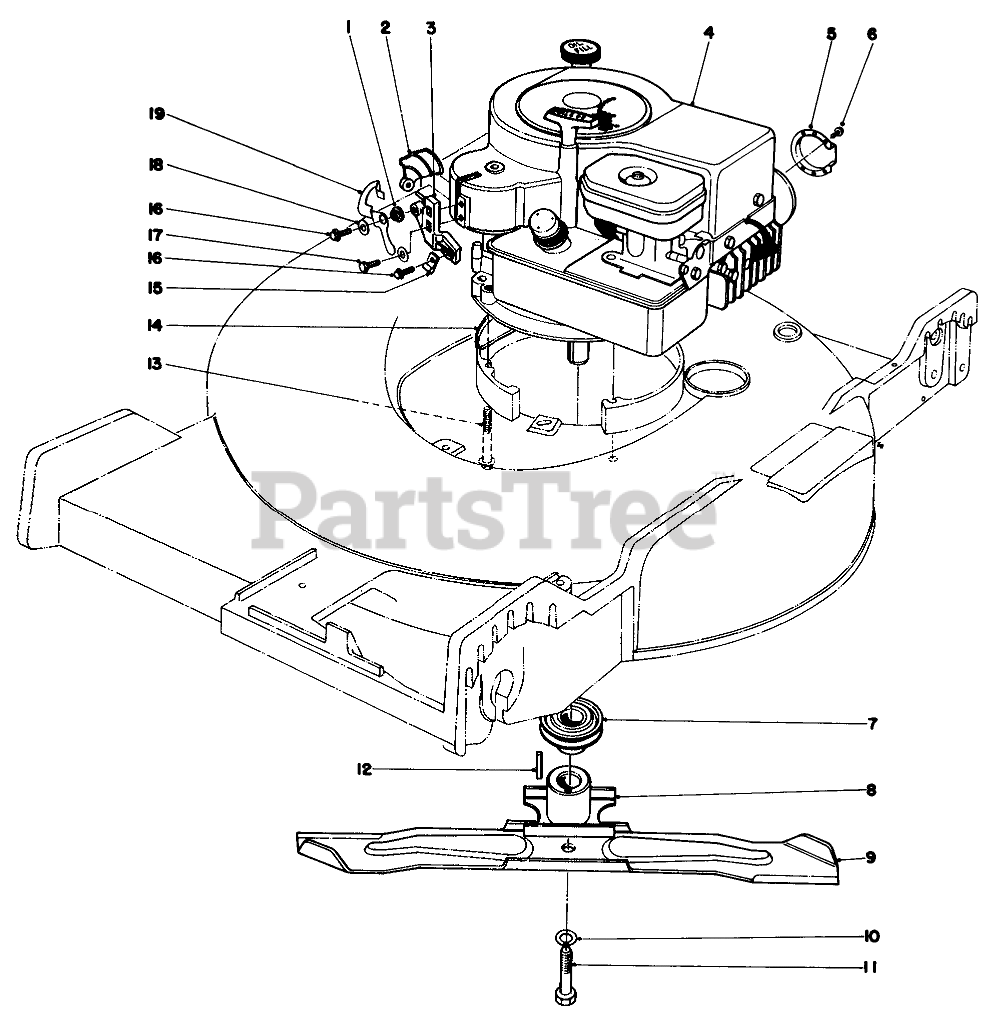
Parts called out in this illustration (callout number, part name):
1	BUSHING
2	INTERLOCK LEVER
3	CABLE & PIVOT BLOCK
4	Engine
5	Deflector
6	SCREW W/ENGINE
7	DRIVER PULLEY
8	BLADE RETAINER WA(BLACK)
9	Blade
10	WASHER-LOCK
11	BLADE SCREW
12	KEY-SQUARE
13	3/8-16 X 2-3/4 CAPSCR
14	HOUSING CAP
15	CLAMP
16	Screw
17	SCREW-SHWH
18	WASHER-FLAT
19	CAM INTERLOCK
